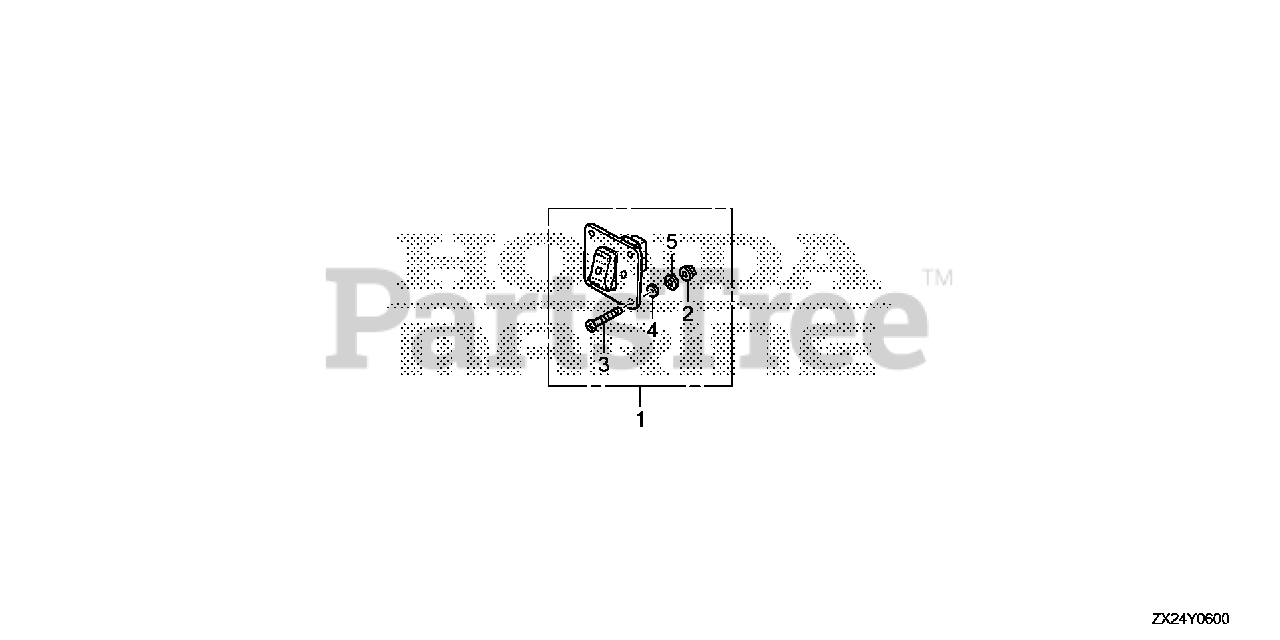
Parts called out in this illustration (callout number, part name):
1	SWITCH KIT, LIGHT
2	NUT, FLANGE (5MM)
3	SCREW, PAN (5X40)
4	WASHER, PLAIN (5MM)
5	WASHER, SPRING (5MM)
